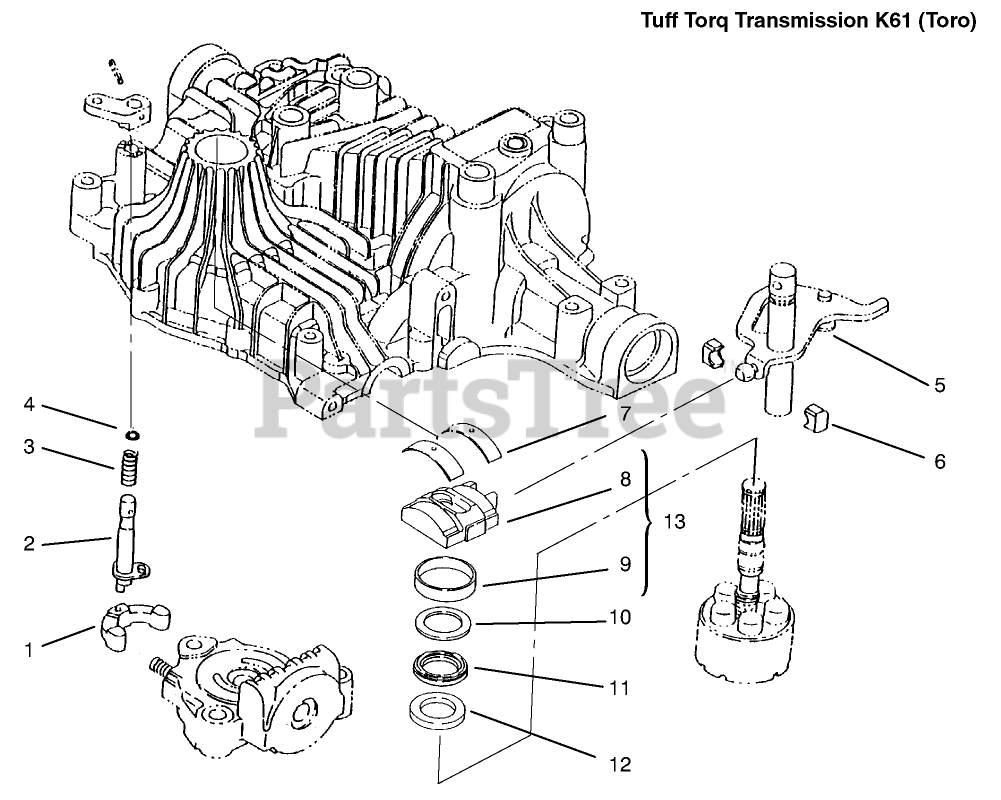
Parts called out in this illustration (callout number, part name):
2	SHAFT-BYPASS
3	SPRING
4	O-RING
5	BLOCK ASM
6	Block-Shift
7	THRUST METAL
8	Plate-Swash
9	Bushing-Swashplate
10	PLATE-THRUST
11	BEARING
12	PLATE - THRUST
13	PLATE-SWASH
